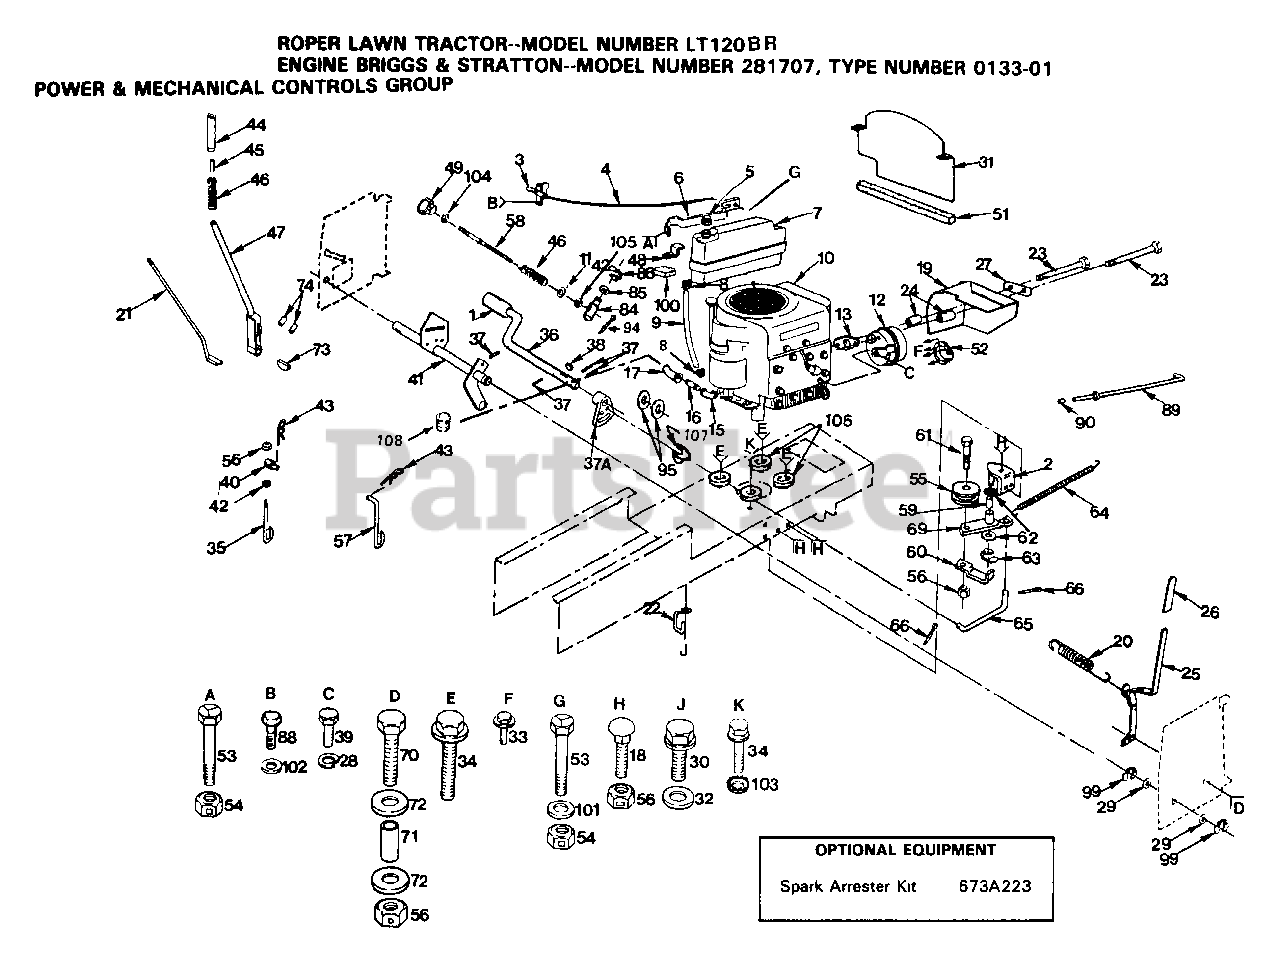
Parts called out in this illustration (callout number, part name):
1	PEDAL COVER T
6	SUPPORT-TANK LT
9	HOSE T
10	ENGINE 12 H.P. TYPE 0201-01
11	WASHER
15	STREET ELBOW LT
16	PIPE NIPPLE
17	ELBOW
18	BOLT
19	BAFFLE ASSY LT
20	"SPRING.EXT.8.5"""
21	ROD ASSY-LEVER LT
23	BOLT YT
24	SPACER LT
27	CLIP-MUFFLER LT
28	LOCKWASHER
29	WASHER
30	SCREW
32	WASHER
33	SCREW LT
34	SCREW LT
35	LINK LIFT LT
36	FOOT SHAFT PEDAL
37A	ARM BRAKE LT
39	BOLT
42	NUT.HEX.3/8-16UNC
44	GRIP
46	SPRING T
47	LEVER ASSY LT
48	BRACE-TANK LT
52	DEFLECTOR.222573
53	BOLT
57	LIFT LINK LT
58	ROD LIFT LT
59	"LY, BEARING"
62	WASHER LT
63	KLIP RING
64	"SPRING, RETURN LT"
65	"LINK, CLUTCH T"
66	COTTER PIN
84	TRUNION LT
85	WASHER
86	KLIP RING
88	SCREW
90	PLUNGER CAP T
99	RING
100	PAD-SPACER T
101	WASHER
103	LOCKWASHER
104	NUT
105	NUT T
107	STREET ELBOW LT
